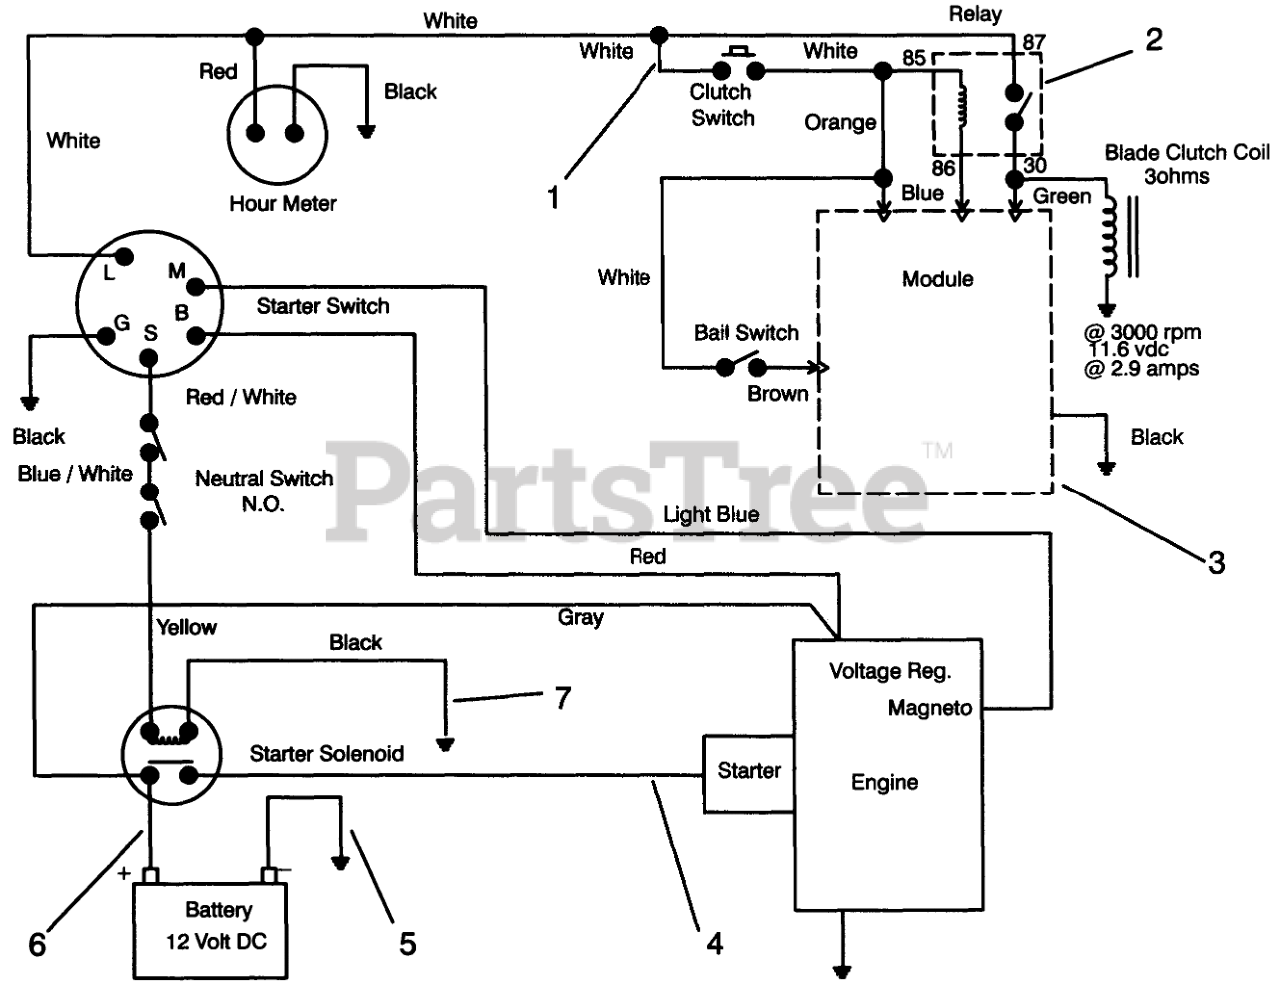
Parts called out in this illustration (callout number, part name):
1	WIRE HARNESS
2	RELAY
3	Module
4	WIRE-SOLENOID/STARTER
5	WIRE ASM
6	WIRE ASM
7	WIRE ASSEMBLY
